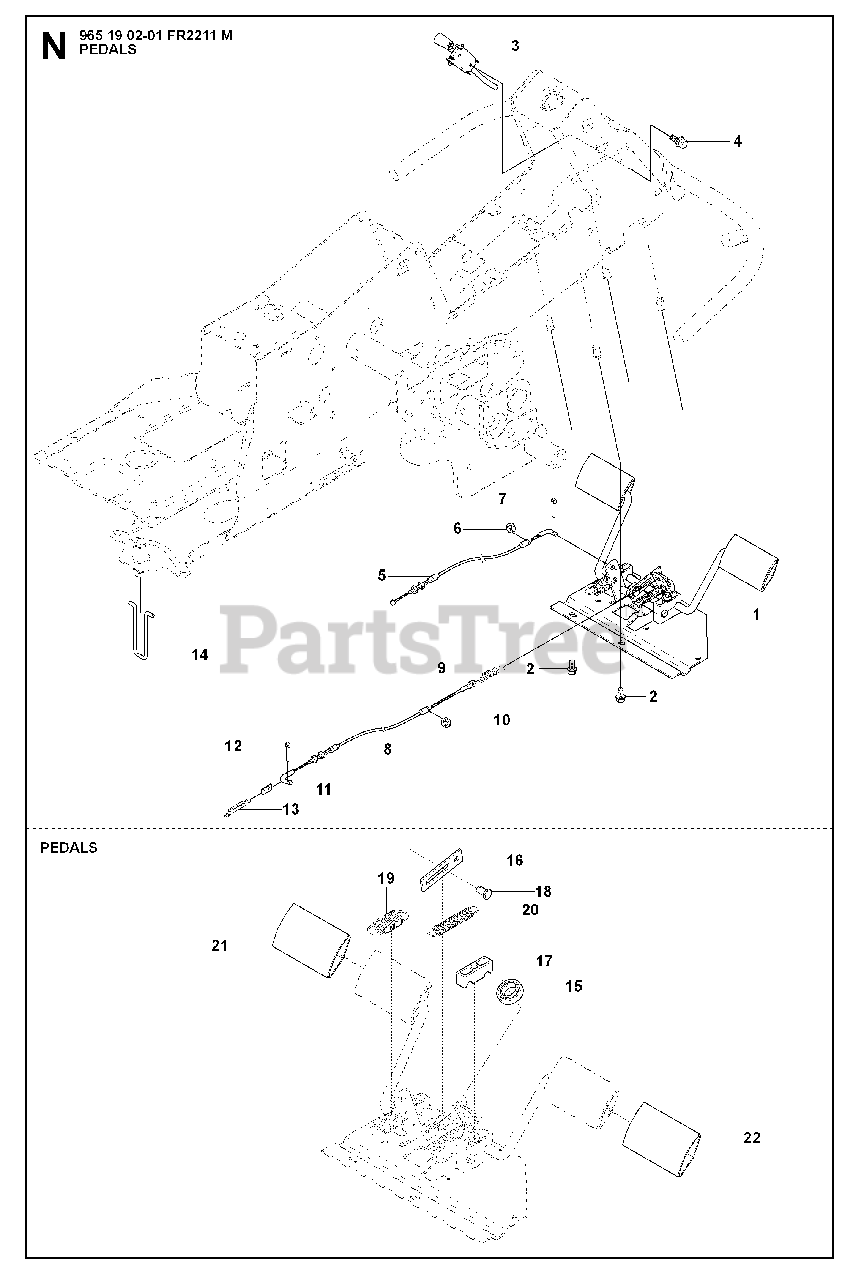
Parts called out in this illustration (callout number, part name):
3	BRAKE LEVER ASSY
7	COTTER PIN
11	CONNECTOR
12	COTTER PIN
15	BALL BEARING 6002-2RS1
17	PEDAL SHAFT CLAMP
18	CLEVIS PIN
21	PEDAL RUBBER, SF
22	PEDAL RUBBER, SF
